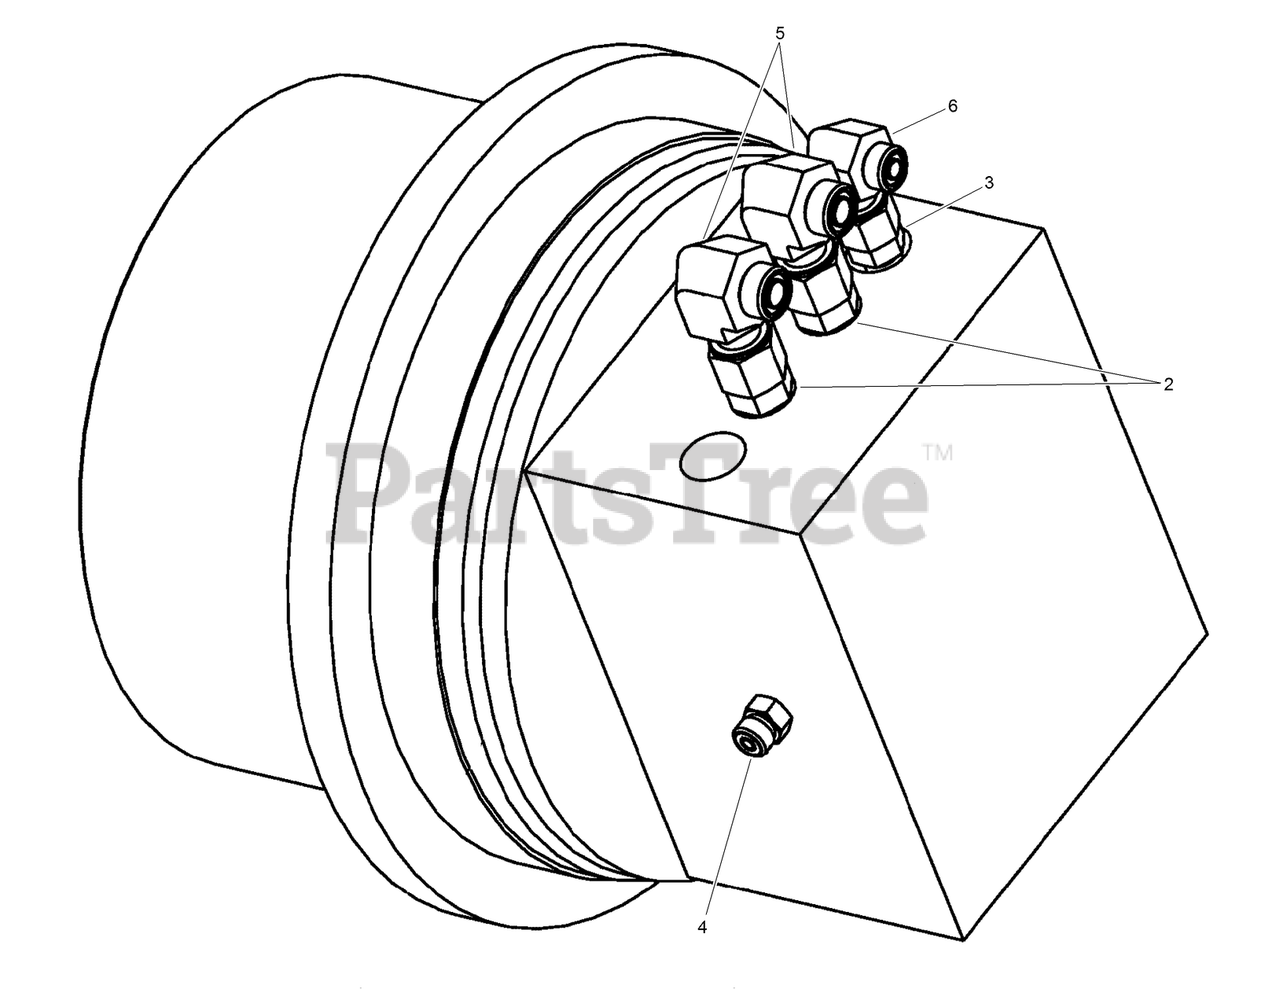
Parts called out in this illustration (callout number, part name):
2	CONNECTION - Straight, -8 ORFS / -8 ORB
3	CONNECTION - Straight, -6 ORFS / -6 ORB
4	CONNECTION - Straight, -4 ORFS / -6 ORB
5	CONNECTION - 90 Deg, -8 ORFS / -8 ORFS
6	CONNECTION - 90 Deg, -6 ORFS / -6 ORFS
